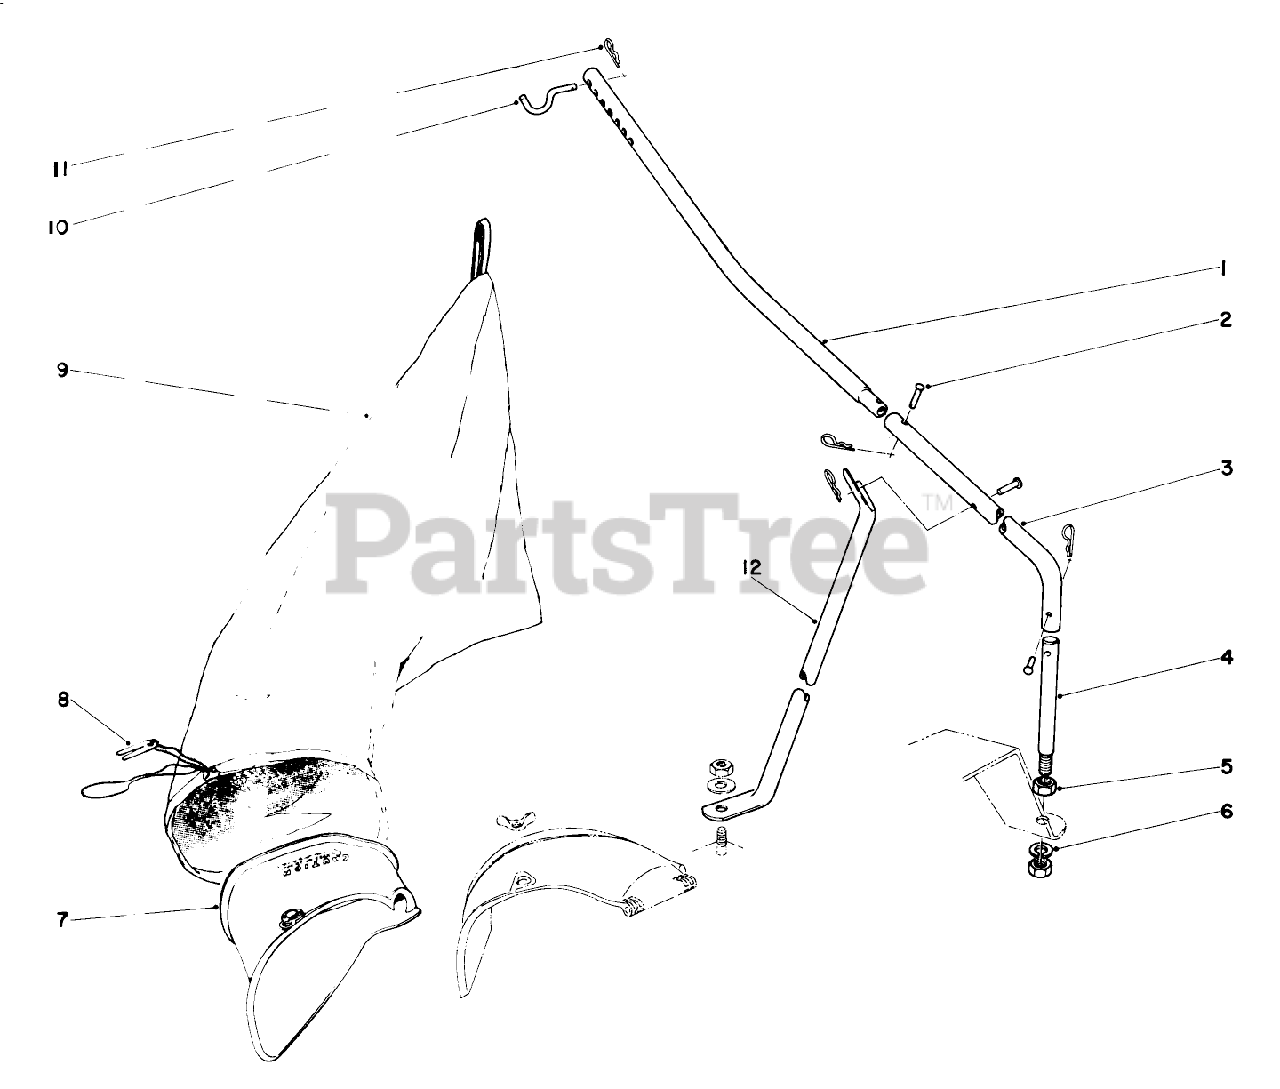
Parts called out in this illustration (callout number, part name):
1	Arm Shaft
3	Bag Arm
4	Bag Attachment Adapter
5	NUT-JAM
6	WASHER-LOCK
7	Bag Attachment
8	BAG CORD FASTENER
9	Bag Assembly
11	PIN-COTTER, HAIR
12	Brace-Bag Arm
